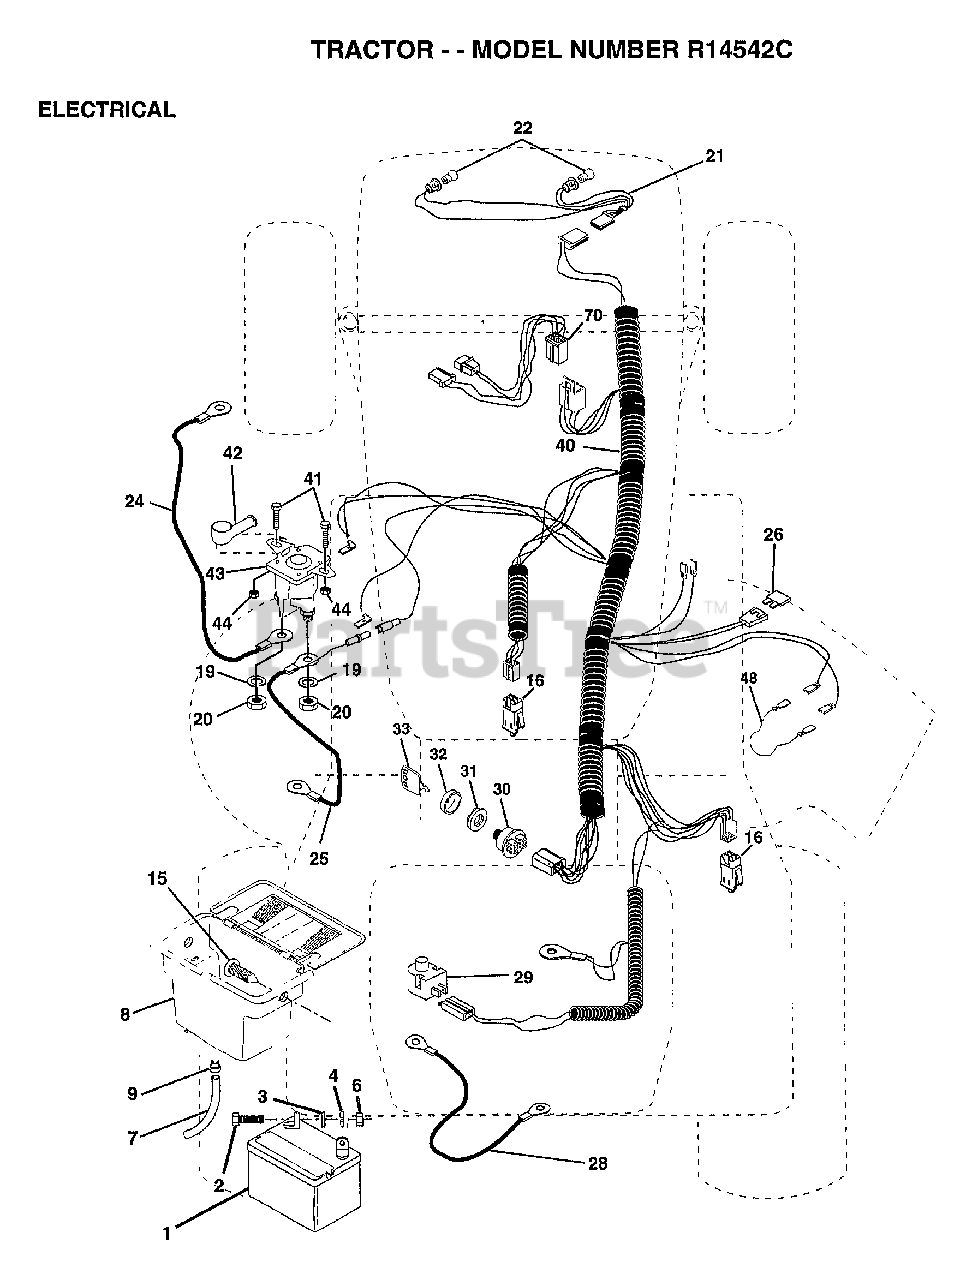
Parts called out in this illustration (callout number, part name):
2	BOLT LT
3	WASHER
4	LOCKWASHER
7	TUBE T
8	"CASE,BATTERY.MECH"
9	HOSE CLAMP T
15	FASTNER.SNAP-IN
16	SWITCH INTERLOCK
20	NUT
21	"HARNESS,LIGHT SOC"
22	HEADLAMP BULB
24	CABLE.BTRY.6GA.RD
25	CABLE.BTRY.6GA.38
26	FUSE HYT
28	CABLE T
29	SWITCH SEAT
30	SWITCH IGN 4POS
31	NUT IGNITION
32	COVER KEY SWITCH
33	KEY
40	HARNESS IGNITION
41	BOLT HXHD FIN
44	NUT HXKEP 1/4X20
48	ADAPTER AMMETER
70	HARNESS.ENG.DUAL
